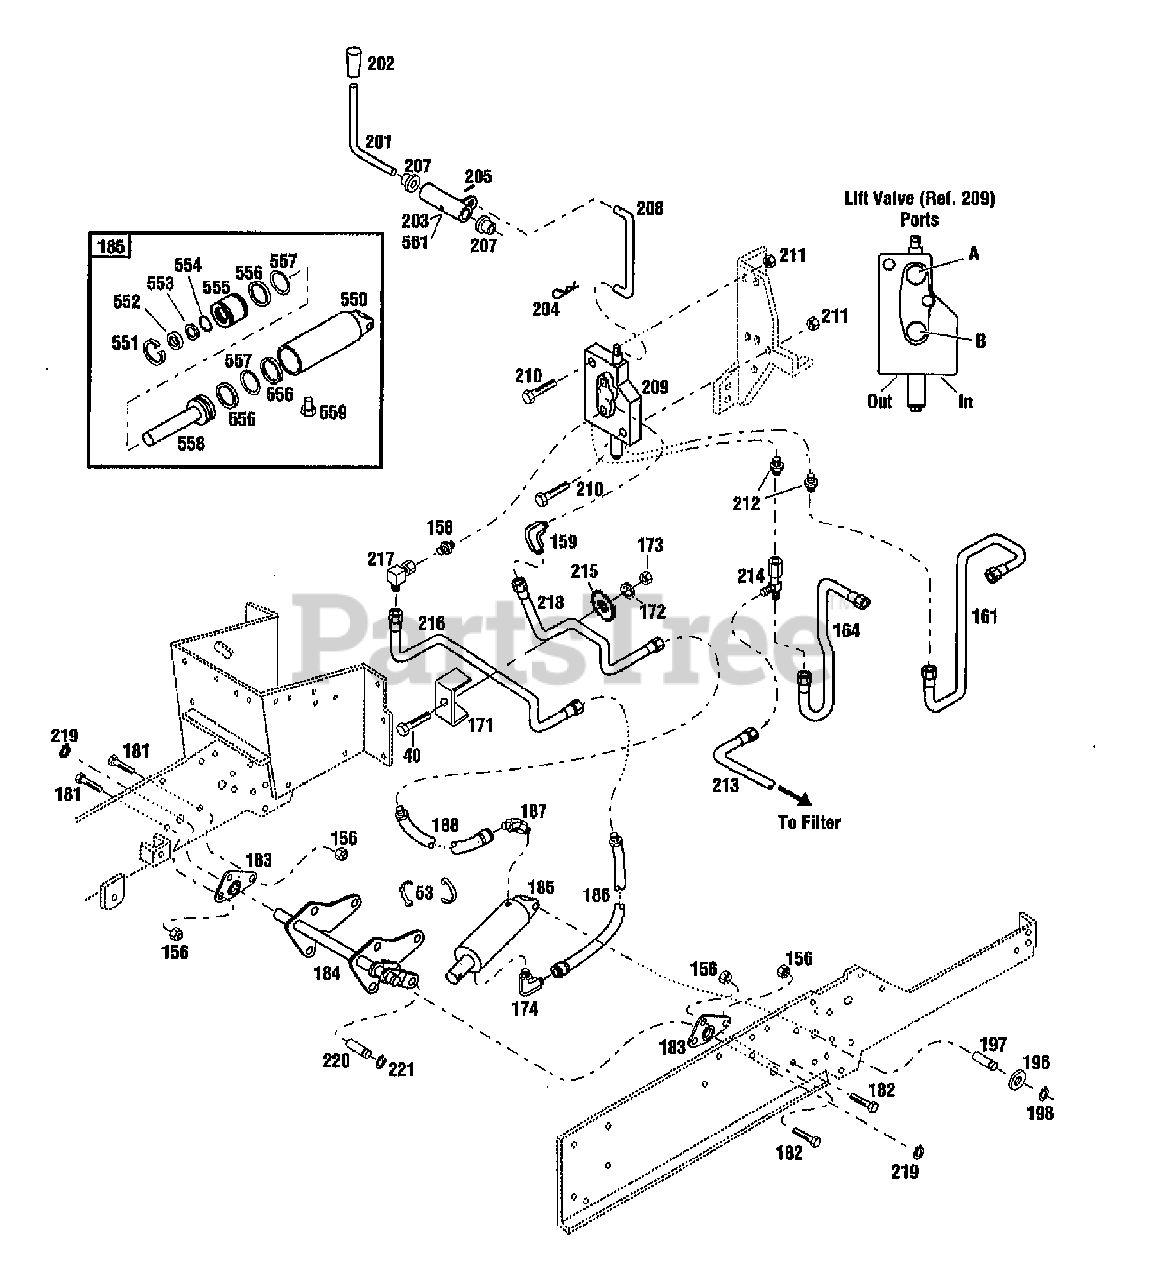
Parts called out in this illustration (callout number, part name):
40	SCR-HH 5/16-18X1.0 G5 ZP
53	CABLE TIE
156	NUT-HFLK 5/16-18 ZP
158	CONNECTOR
159	ELBOW
161	TUBE-HYD PB VALVE
164	TUBE-HYD S C U TANK
171	CLAMP
172	WASHER-LK .312 ZP
173	NUT-HEX 5/16-18 ZP
174	ELBOW
181	SCR-LOCK
182	SCR-LOCK
183	BEARING-LIFT SHAFT
185	ASSM-CYL HYDRAULIC
186	ASSM-HOSE
187	ELBOW
188	ASSM-HOSE
196	WASHER-1.5X.755X.062
198	RING-RETAIN EXT .707 ID
201	LEVER-CONTROL
202	KNOB-SHIFT LEVER
203	ARM-CONTROL
204	PIN-CLIP .08
205	PIN-DRIVE
207	BRG-FLANGE
208	LINK-VALVE
209	VALVE-HYDRAULIC
210	SCR-HFLK 1/4-20X2.00 G5ZP
211	NUT-HF/LK 1/4-20 ZP
212	CONNECTOR
213	TUBE-HYD RETURN
214	TEE-SWIVEL
215	WASHER-FLAT 1.25X.406X.179
216	TUBE-HYD VALVE TO ROD
217	ELBOW
218	TUBE-HYD VALVE TO HEAD
219	RING-RETAINING
221	RING-RETAIN .625 ID
550	ASSM-CYL HYDRAULIC
551	RING-RETAIN INT 2.210 DIA
552	SEAL-OIL
553	RING-BACK/UP
554	RING-O .984 ID
555	HEAD-CYLINDER
556	RING-BACK/UP
557	RING-O 1.6 ID
558	ASSM-ROD HYDR CYLINDER
559	PLUG-PIPE
561	ARM-CONTROL
